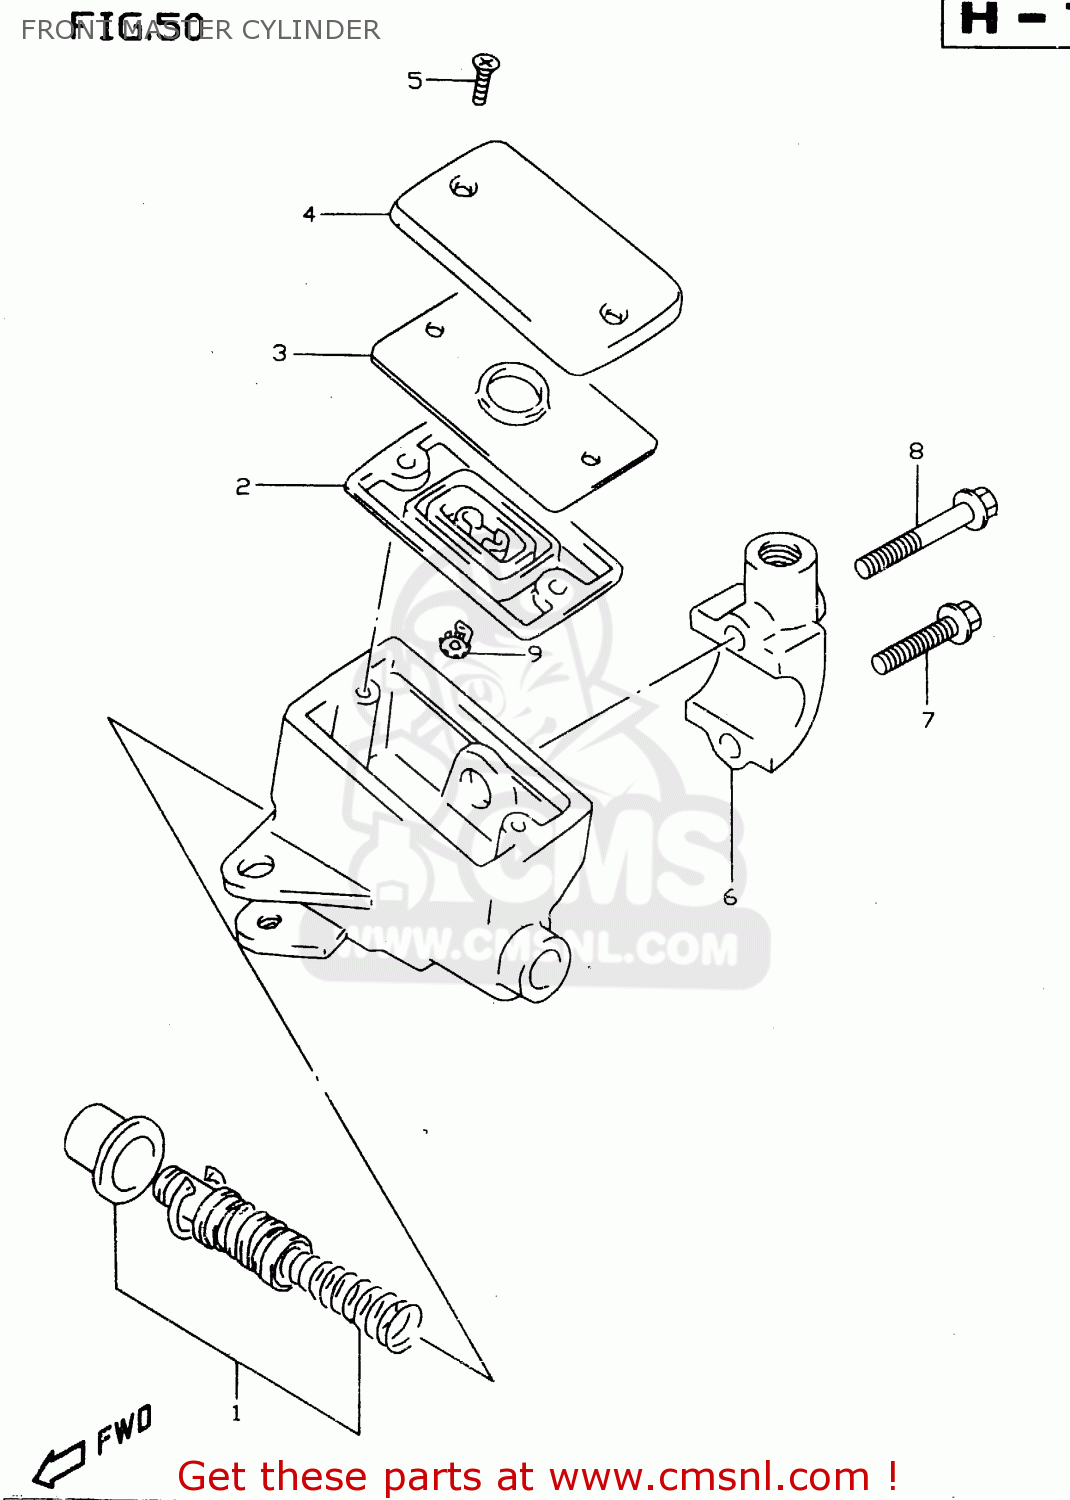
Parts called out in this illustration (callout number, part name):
1	PISTON & CUP SET
2	3
3	PLATE,DIAPHRAGM
4	CAP
5	SCREW
6	HOLDER
7	BOLT(6X25)
8	BOLT(6X38)
9	PROTECTOR
